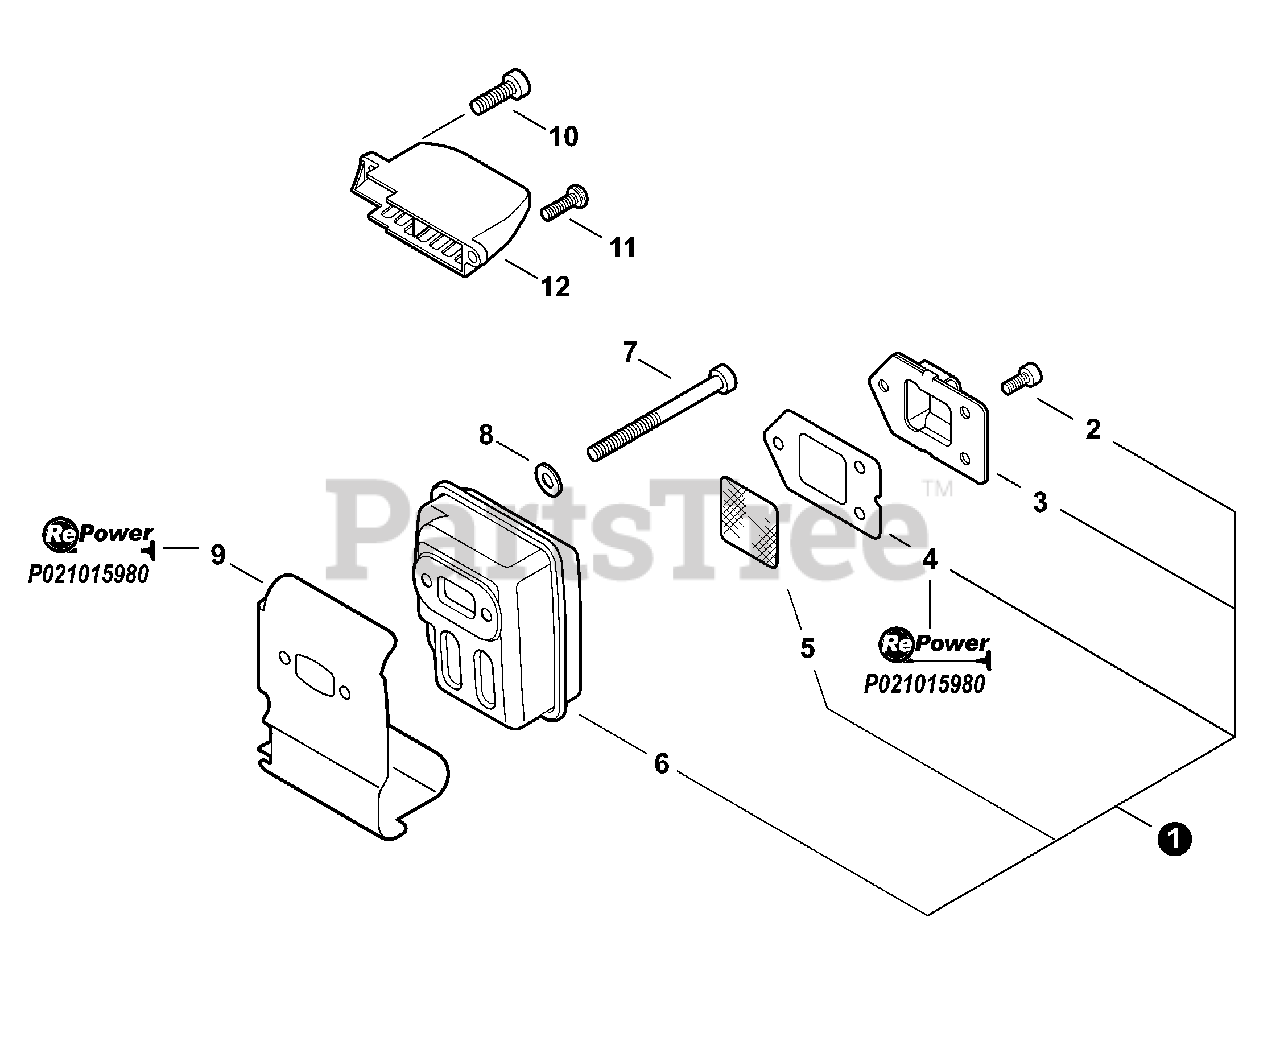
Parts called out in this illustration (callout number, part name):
1	MUFFLER ASSY
2	SCREW - 4×8 -- TORX
3	GUIDE, EXHAUST
4	GASKET, EXHAUST
5	SCREEN, SPARK ARRESTER
7	SCREW - 5×55
8	WASHER - CONICAL
9	SHIELD, EXHAUST
10	SCREW - 5×16
11	SCREW - 5×16
12	DUCT, AIR
